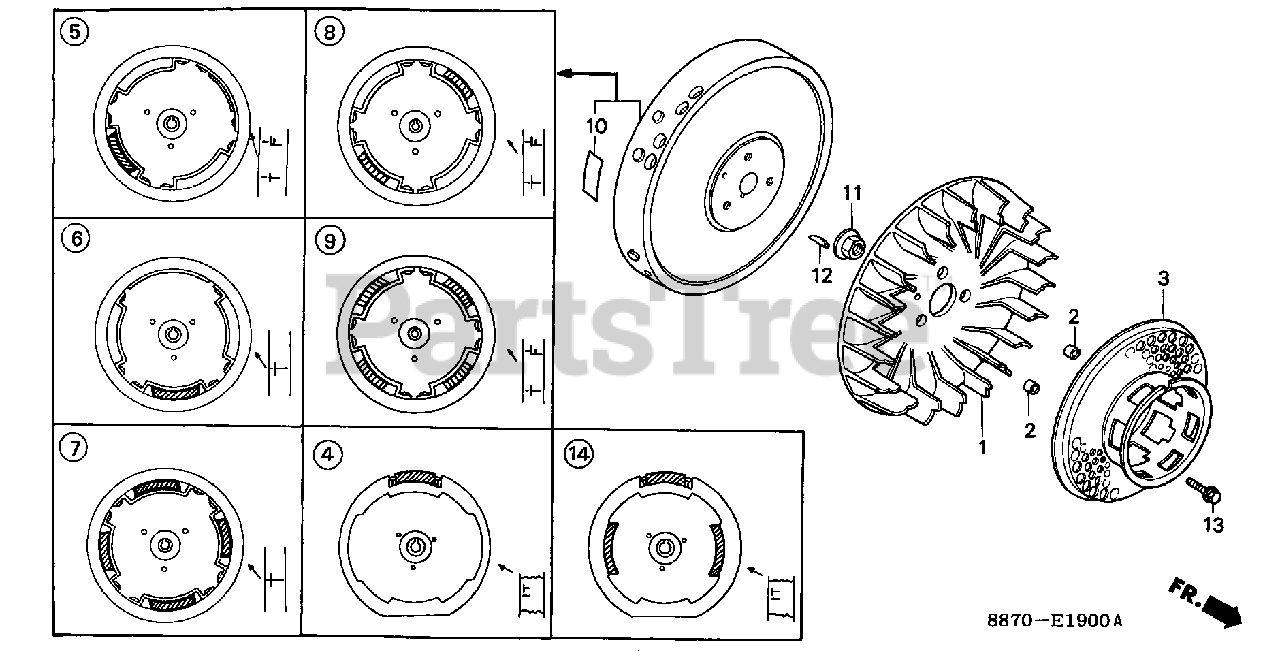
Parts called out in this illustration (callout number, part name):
1	FAN, COOLING
2	COLLAR, FAN
3	PULLEY, STARTER
5	FLYWHEEL (POINT)
10	MARK, FLYWHEEL CAUTION
11	NUT, SPECIAL (14MM)
12	KEY, SPECIAL WOODRUFF (25X18)
13	BOLT, FLANGE (6X16)
